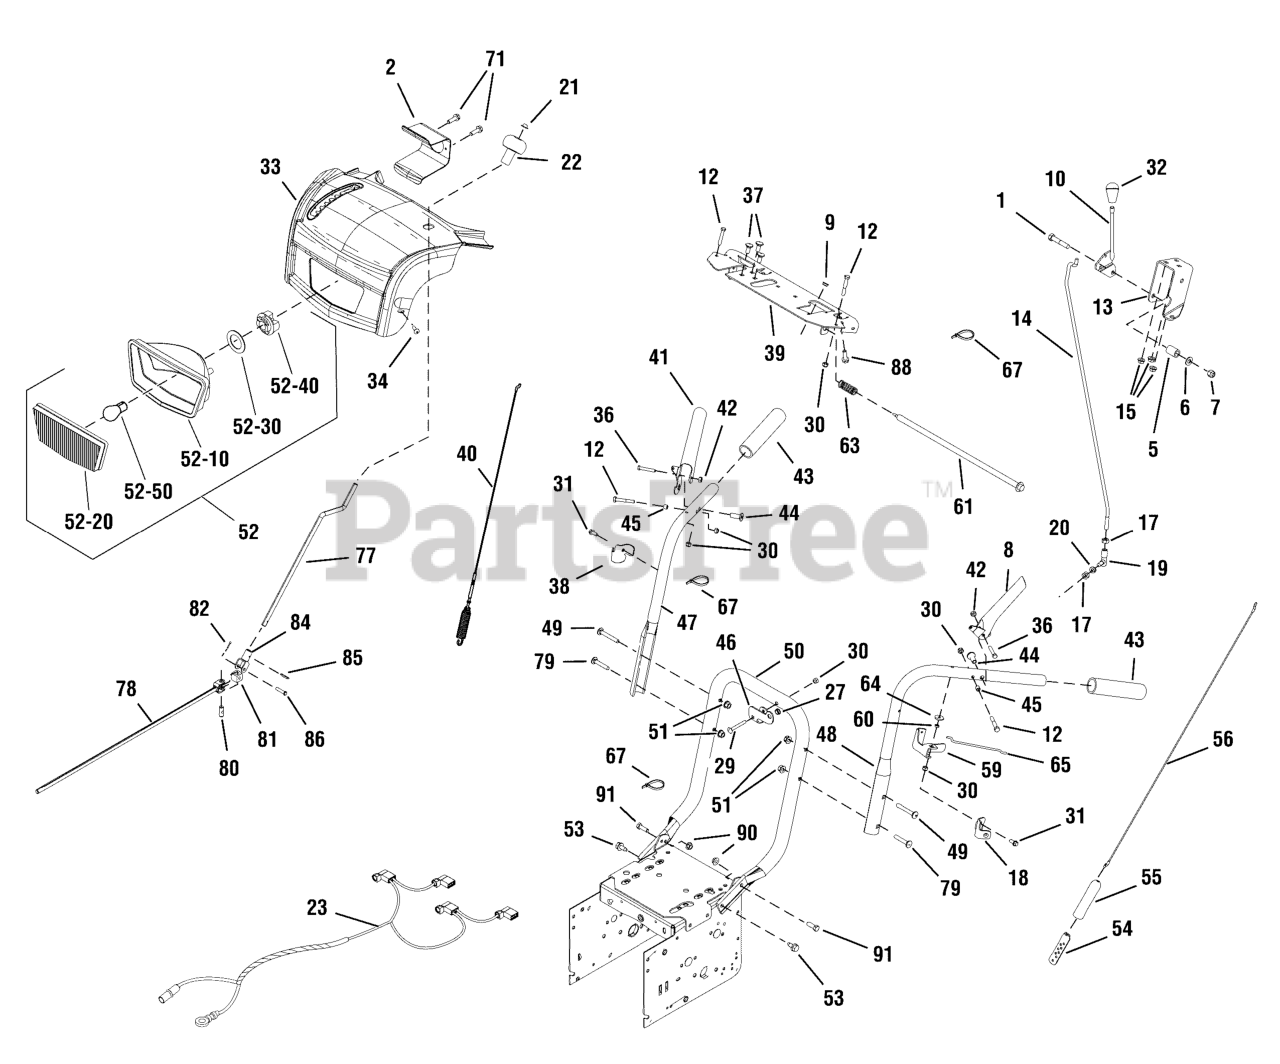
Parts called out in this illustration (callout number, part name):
1	CAPSCREW, Hex Head, 3/8-16 x 2, GR5
2	BRACKET, Light Mount
5	SPRING, 3/4"
6	WASHER, 3/8
7	NUT, Hex Lock, ESNA LIGHT, 3/8-16
8	LEVER-CLUTCH LH PLASTISOL DIP
9	BUSHING, Nylon, 3/8 ID x 7/16 OD x 2"
10	ROD & BRACKET ASSEMBLY, Speed
12	CAPSCREW, Hex Head, 1/4-20 x 1-3/4, GR5
13	BRACKET, Trac & Deflector Control
14	ROD, 25-3/8"
15	NUT, Hex Flange Whiz Lock Small, 5/16-18
17	NUT, Hex, 5/16-24
18	BRACKET, Mounting, Panel, Left
19	BALL JOINT
20	WASHER, Lock Helical Spring
21	NUT, Push Pal, 3/8
22	KNOB, Spinner
23	WIRING HARNESS, Headlights
27	BUSHING, Chute Crank
29	BOLT, Carriage, Short Neck, 1/4-20 x 2, GR5
30	NUT, Hex Lock, ESNA Light, 1/4-20
31	CAPSCREW, Hex Washer Head, Taptite, 1/4-20 x 5/8
32	KNOB, Hole, .357 Diameter 1.14 Diameter, Sphere Softer
33	COVER ASSEMBLY, Panel
34	SCREW, Pan Head Torx, Taptite, 1/4-20 x 3/4
36	CAPSCREW, Hex Head, 1/4-20 x 1-1/2, GR 5
37	BOLT, Carriage, Short Neck, 5/16-18 x 3/4, GR 5
38	BRACKET, Mounting, Panel, Right
39	SUPPORT-DASH PANEL
40	CABLE & SPRING ASSEMBLY, Auger Drive, RH
41	LEVER, Clutch, RH
42	NUT, Hex Centerlock, 1/4-20
43	HAND GRIP
44	SPACER, Stepped
45	SPACER, 1/4 ID x 3/8 OD x 5/16"
46	BRACKET, Rod Support
47	HANDLE, Upper, RH
48	HANDLE, Upper, LH
49	BOLT, Carriage, 5/16-18 x 2-1/4, GR5
50	HANDLE, Lower Tubular
51	NUT, Hex Flange Nylock, 5/16-18
52	HEADLIGHT ASSEMBLY
52-10	DEFLECTOR, Headlight
52-20	LENS, Headlight
52-30	GASKET, Light
52-40	SOCKET & GASKET ASSEMBLY, Headlight
53	SCREW, Taptite, 5/16-18 x 3/4
54	BRACKET, Cable Adjusting
55	BOOT, Spring End Cover
56	CABLE, Front Drive
59	BRACKET, Pivot, Free Hand
60	SPACER, 1/4 ID x 3/8 OD x 1/8"
61	ROD & SPRING ASSEMBLY
63	SPRING, Compression, 2-1/4"
64	WASHER, 1/4 x 27/32 OD
65	ROD, Hold Down, 5-5/8"
67	TIE, Self Locking, 15" Long
71	CAPSCREW, Hex Washer Head, #10-HL x 5/8
77	CRANK, Chute Handle
78	ROD AND YOKE
79	BOLT, Carriage, Short Neck, 5/16-18 x 1-3/4, GR 5
80	PIN, Universal Joint, 3/8 x 1
81	BLOCK, Universal Pivot
82	PIN, Cotter
84	YOKE AND TUBE, Chute
85	PIN, Hair, Chute Gear
86	PIN, Clevis, 1/4 x 1.09
88	SCREW, 1/4-15X3/4, Self-Tapping, BZ
90	NUT, Hex Flange, Two Way Lock, 5/16-18
91	CAPSCREW, Hex Head, 5/16-18 x 1
